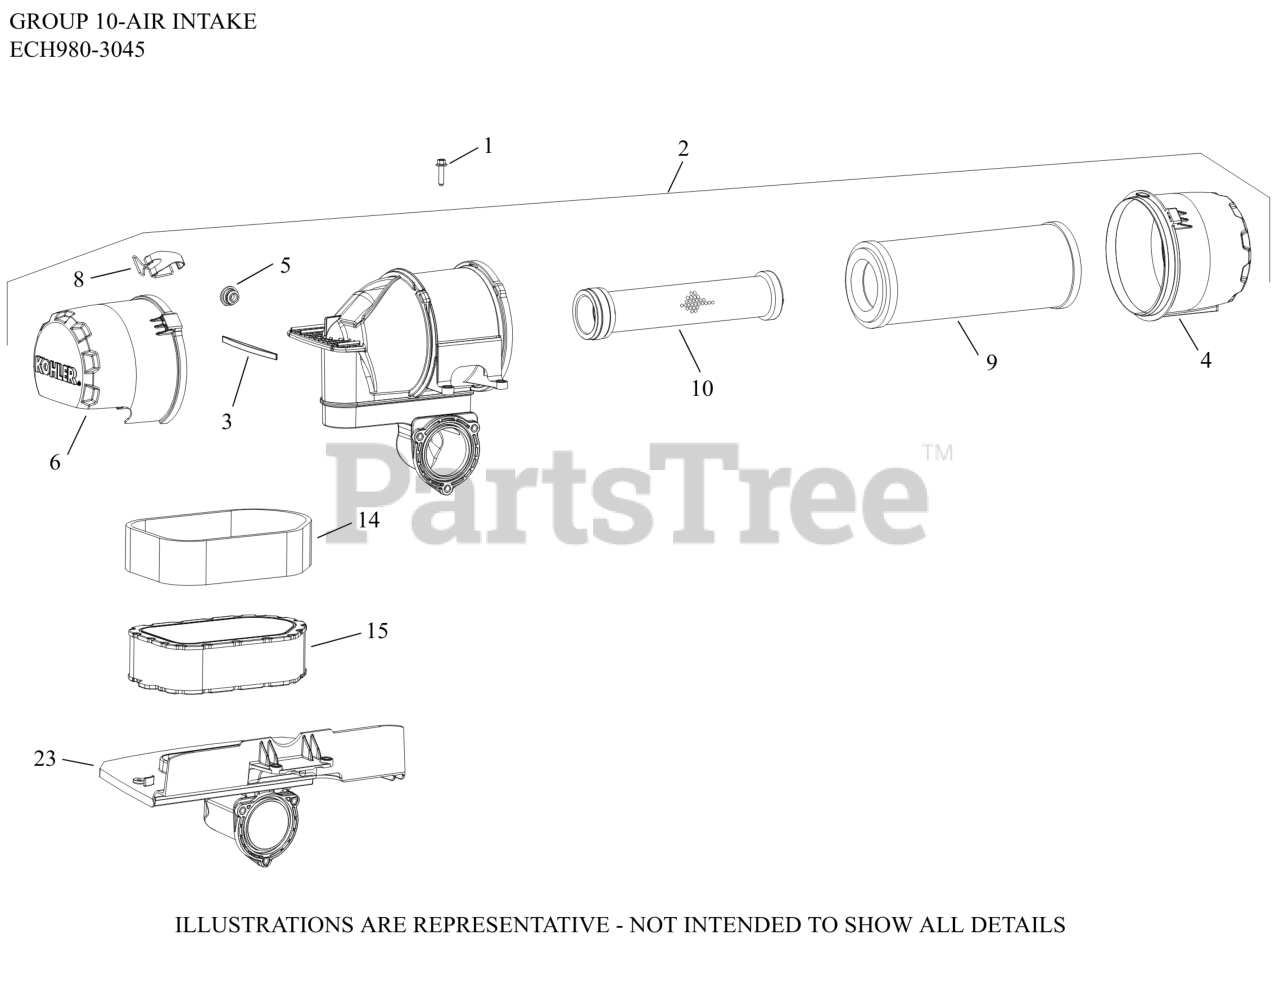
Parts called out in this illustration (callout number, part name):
1	SCREW, FLG M6X1.0X25
2	FILTER ASSEMBLY, AIR
3	DAMPER, FOAM INSERT
4	COVER, AIR FILTER
5	PLUG, HOLE
6	COVER, RAIN CAP
8	CLIP ASSEMBLY
9	ELEMENT, AIR FILTER - PRIMARY
10	ELEMENT, AIR FILTER - SAFETY
23	BASE, AIR CLEANER
